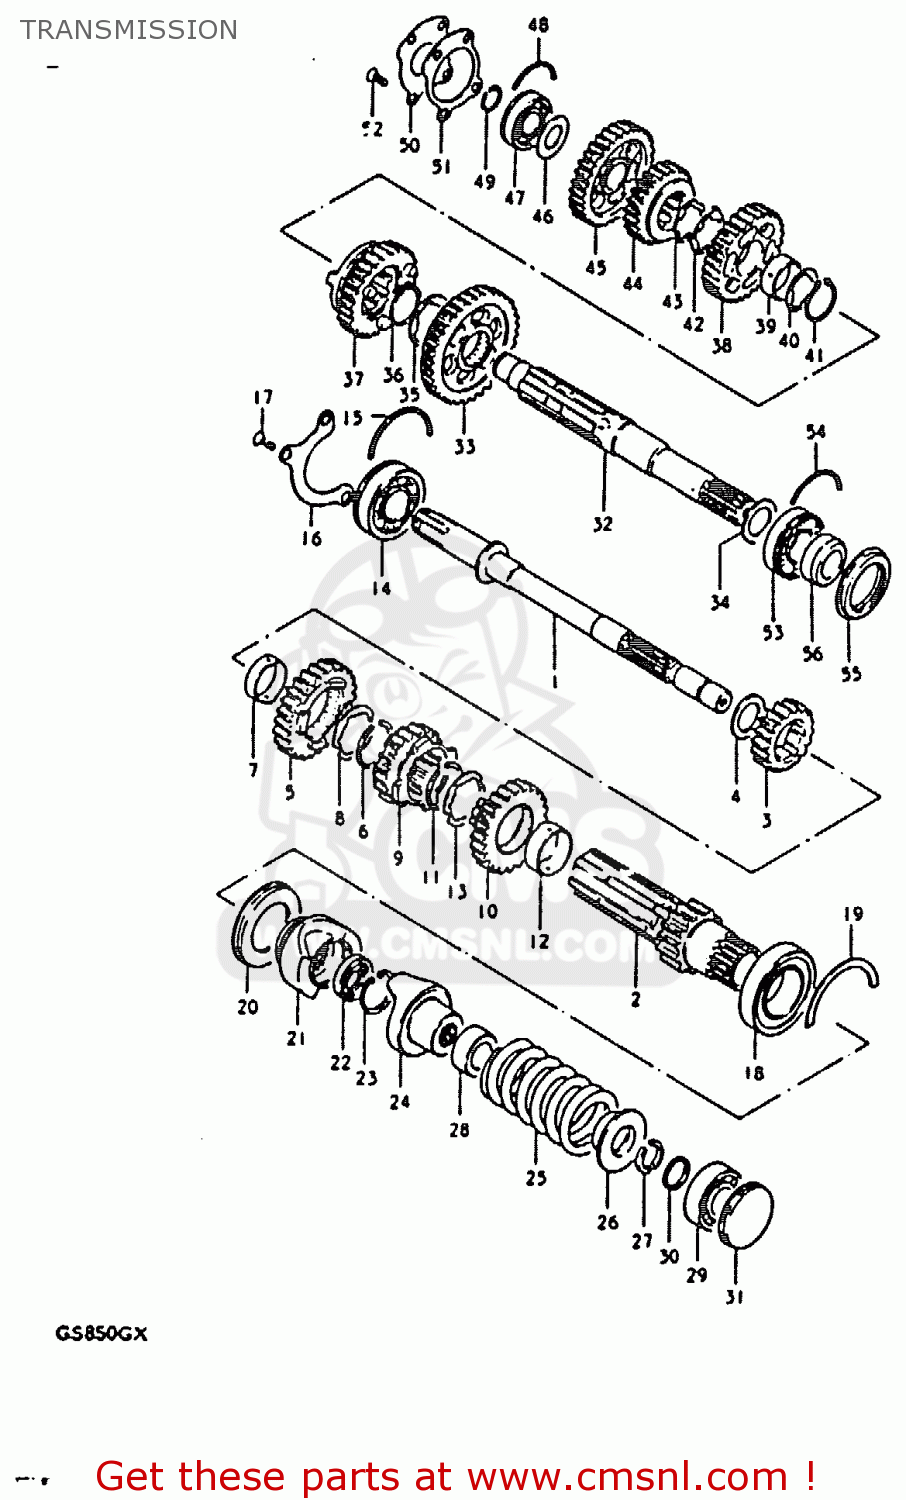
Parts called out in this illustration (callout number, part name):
1	SHAFT,COUNTER
2	SHAFT,OUTER COUNTER
3	GEAR,SECOND DRIVE
4	WASHER (21X35X2)
5	GEAR,5TH DRIVE(NT:26)
6	RING,SNAP
7	SPACER,DRIVE GEAR
8	LOCK WASHER,5TH DR GEAR SPACER
9	GEAR,THIRD DRIVE
10	GEAR,FOURTH DRIVE
11	RING,SNAP
12	SPACER,DRIVE GEAR
13	LOCK WASHER,5TH DR GEAR SPACER
14	BEARING(25X62X17)
15	C-RING
16	RETAINER,CNTR SHAFT BEARING
17	SCREW
18	BALL BEARING 32X58X13
19	C-RING
20	SEAL,OIL(40X58X7)
21	DOG,OUTPUT CAM
22	SEAL,OIL(20.6X31X6)
23	CIRCLIP
24	DOG,INPUT CAM
25	SPRING
26	STOPPER,CAM DOG
27	STOPPER,CAM DOG
28	GUIDE,CAM DOG SPRING
29	BEARING
30	SPACER (17X21X3.5)
31	PLUG
32	SHAFT,DRIVE
33	GEAR,FIRST DRIVEN
34	WASHER, LH
35	WASHER,LOCK
36	CIRCLIP
37	GEAR,FOURTH DRIVEN
38	GEAR,THIRD DRIVEN
39	BUSH,3RD DRIVEN GEAR
40	WASHER,LOCK
41	CIRCLIP
42	WASHER
43	WASHER,LOCK
44	GEAR,FIFTH DRIVEN
45	GEAR,SECOND DRIVEN
46	WASHER
47	BEARING(20X47X14)
48	C RING
49	CIRCLIP
50	PLATE,DRIVESHAFT
51	GASKET,DRIVESHAFT PLATE (MCA)
52	SCREW
53	BEARING
54	C RING
55	SEAL,OIL(35X52X6)
56	SPACER,DRIVESHAFT,LEFT
